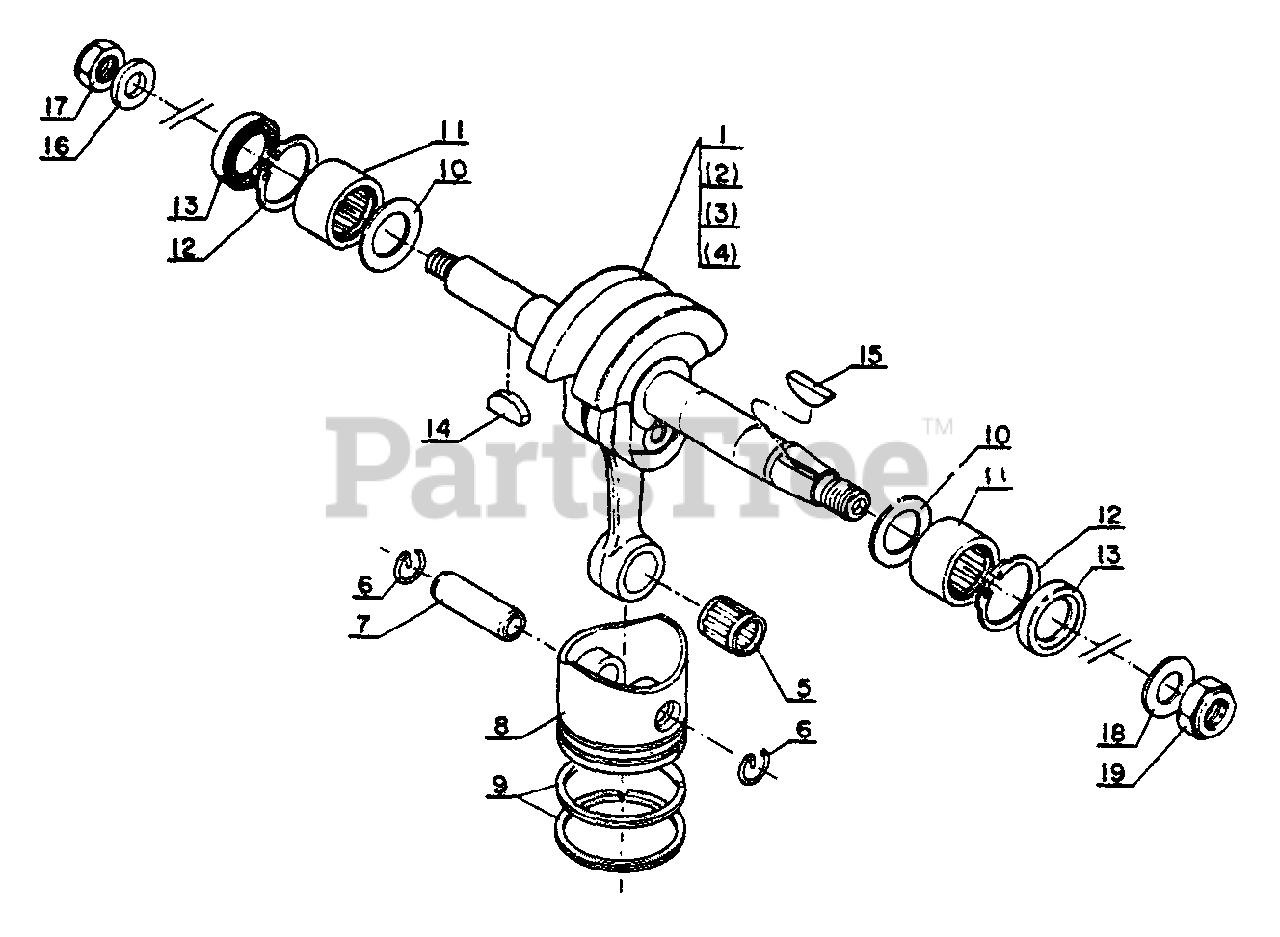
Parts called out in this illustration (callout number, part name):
1	CRANKSHAFT ASSY
5	BEARING, NEEDLE
6	RING, RETAINING
7	PIN, PISTON
8	PISTON
9	RING, PISTON
10	PLATE, SIDE
11	BEARING, NEEDLE
12	RING, RETAINING
13	SEAL, OIL
16	WASHER - 6
17	LOCKNUT - 6
18	WASHER - 8
19	LOCKNUT
